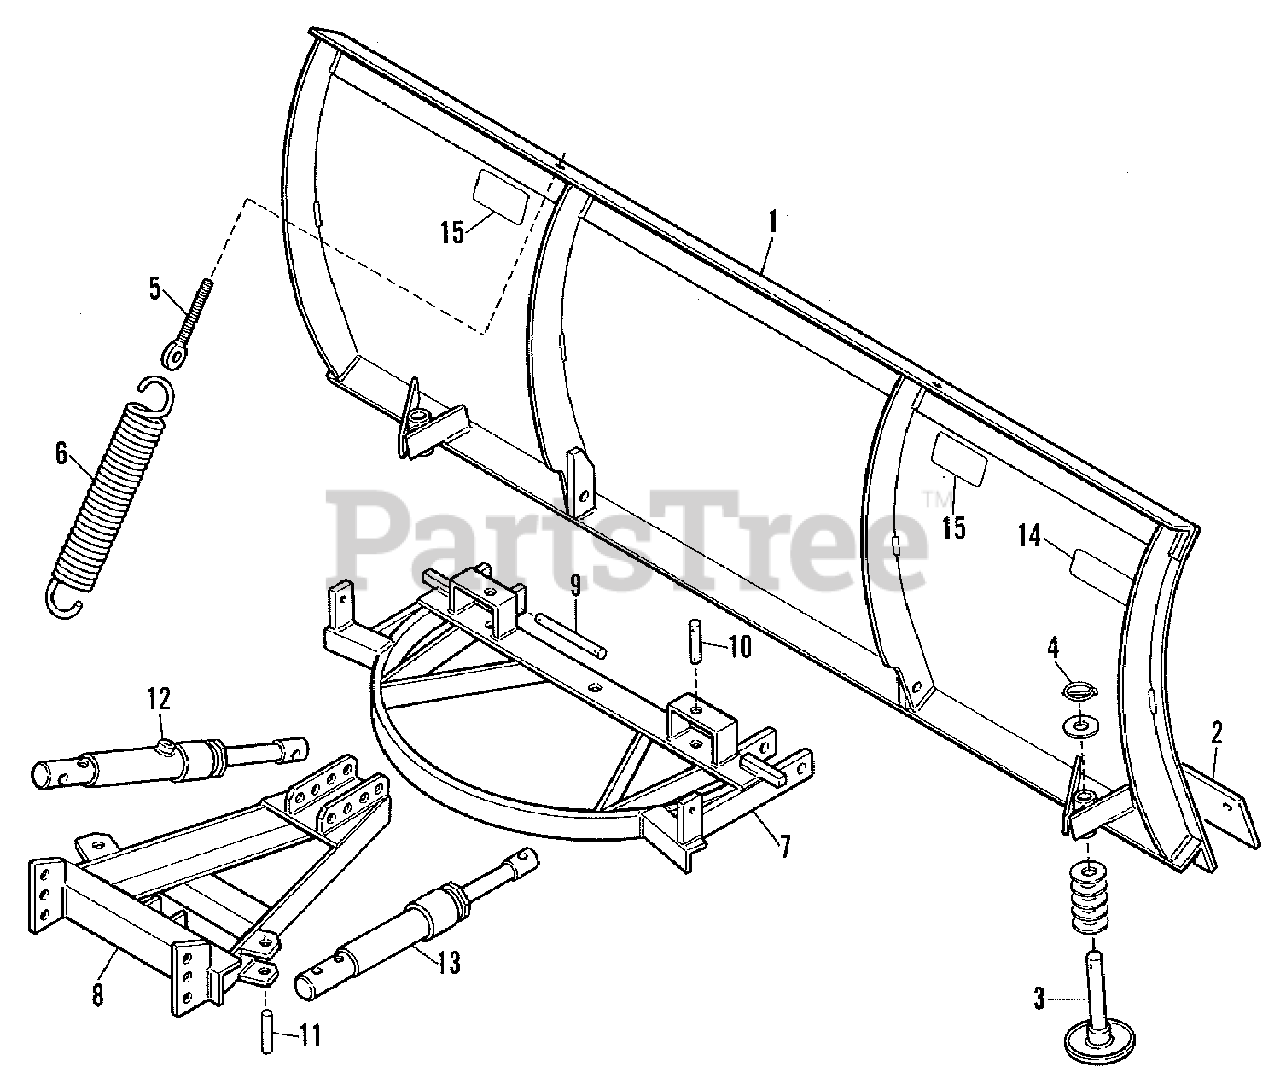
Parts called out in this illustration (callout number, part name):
1	BLADE ASSEMBLY (72")
2	EDGE, Blade
2	BOLT, Carriage, 1/2NC x 1-1/2
2	LOCKWASHER, 1/2
3	SKID, Blade
3	WASHER, Plain, 1-1/16 x 2-3/8 x 7 Ga.
4	PIN, Quick Hitch
5	ADJUSTER, Spring Trip
6	SPRING, Trip
7	SECTOR ASSEMBLY
8	FRAME ASSEMBLY
8	CAPSCREW, 3/4NC x 2-1/2
8	NUT, Lock, 3/4NC
9	PIN, Cotter, 3/16 x 2
10	PIN, Angle Cylinder, Front
10	PIN, Cotter, 3/16 x 2
11	PIN, Angle Cylinder, Rear
11	PIN, Cotter, 3/16 x 2
12	CYLINDER ASSEMBLY, Complete
13	CYLINDER ASSEMBLY, Complete
14	DECAL (Model 410 Identification)
15	DECAL (Warning)
